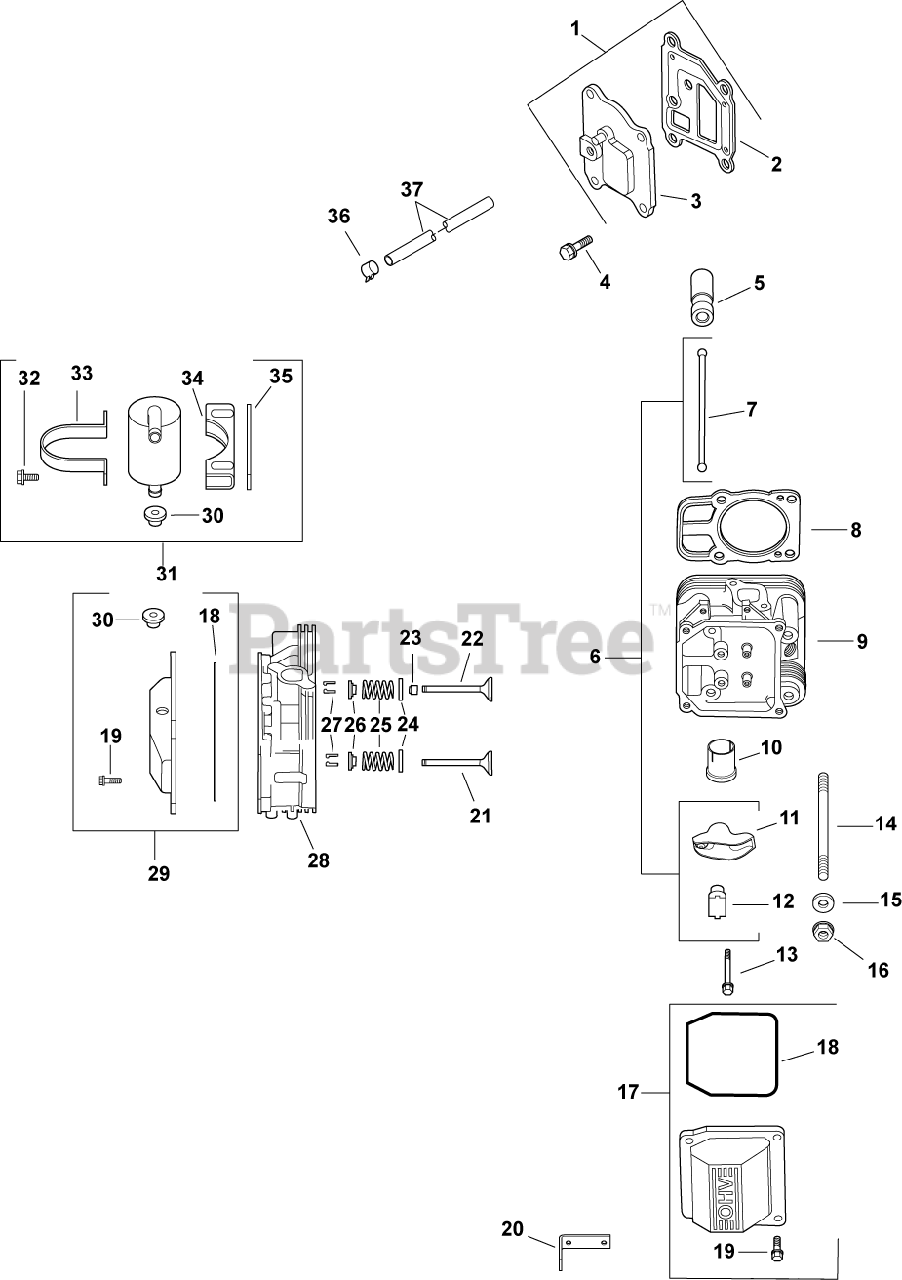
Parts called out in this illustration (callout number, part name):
1	KIT, BREATHER COVER W/GASKET
2	GASKET, BREATHER-USE 24 041 67-S
3	COVER, BREATHER -USE 24 096 125-S
4	SCREW,FLG THD FRM M6X1.0X20-(#25086396S)
5	LIFTER, HYDRAULIC VALVE-USE 25 351 10-S
6	KIT, VALVE TRAIN
7	ROD, PUSH
8	CYL HEAD GASKET KIT-USE 24 841 04-S
9	HEAD, ASSEM CYLINDER #2 -USE 24 318 116-
10	LINER, EXHAUST PORT-USE 24 605 07-S
11	ARM, ROCKER
12	PIVOT, ROCKER ARM
13	SCREW, FLG M6X1.0X34
14	STUD, M8X1.25
15	WASHER, FLAT 8.6 MM
16	NUT, FLG M8X1.25
17	KIT, VALVE COVER-PLAIN
18	O-RING (YELLOW) -USE 24 153 30-S
19	SCREW, FLG M6X1.0X30
20	STRAP, LIFTING-USE 25 445 03-S
21	VALVE, EXHAUST (STD) - USE 32 016 01-S
22	VALVE, INTAKE (STD)
23	SEAL, VALVE STEM - (#2503214S)
24	RETAINER, SPRING
25	SPRING, VALVE
26	RETAINER, VALVE SPRING - USE 25 173 28-S
27	KIT, RETAINER
28	HEAD, ASSEM CYLINDER #1 -USE 24 318 108-
29	KIT, VALVE COVER
30	GROMMET, RUBBER
31	KIT, BREATHR SEPARATR-(#24755241S)
32	SCREW,FLG THD FRM M5X0.8X16-(#25086398S)
33	STRAP, BREATHER - USE 24 755 241-S
34	BRACKET, BREATHER SEPARATOR
35	SPACER
36	CLAMP, HOSE (KM)-USE 25 237 31-S
37	HOSE, BREATHER-USE 24 326 63-S
2401602-S	VALVE, EXHAUST (.25)
2401702-S	VALVE, INTAKE (.25)
